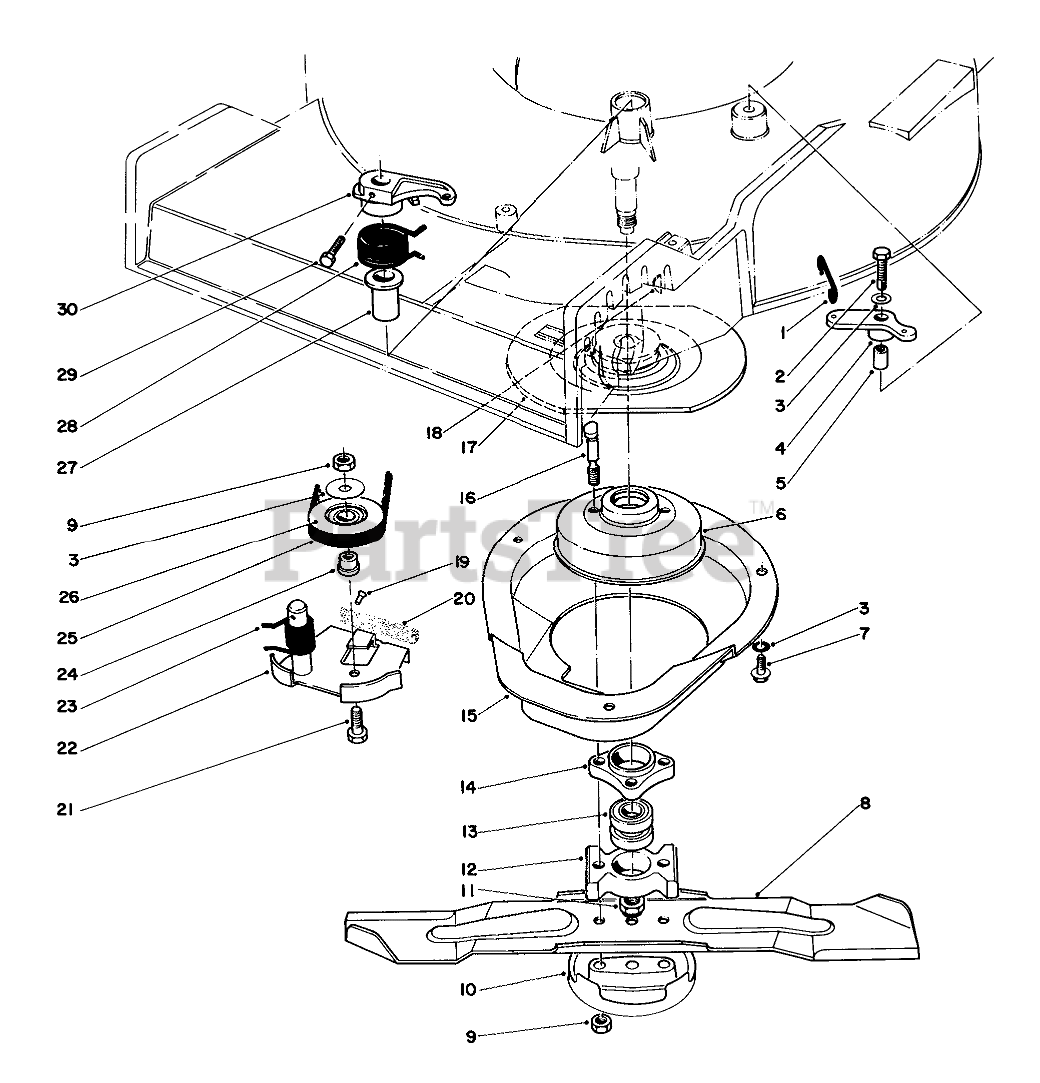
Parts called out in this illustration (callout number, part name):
1	Link Control
2	SCREW-HH
3	WASHER-FLAT
4	Bell Crank
5	Sleeve-Bell Crank
6	Brake Drum
7	SCREW-HWHTF
8	BLADE-21in
9	NUT-LOCK, NI
10	Anti Scalp Cup
11	NUT-LOCK, NI
12	Spacer Blade
13	BEARING-BALL
14	Hub Assembly (Incl. Ref. #13)
15	Shield
16	BOLT-BLADE
17	Flywheel
18	KEY-WOODRUFF
19	.185 DIA X .375 RT +
20	Paid
21	SCREW-HH
22	Brake Plate
23	SPRING-TORSION
24	HUB-PULLEY, IDLER
25	V-Belt
26	PULLEY-IDLER
27	BUSHING PM
28	TORSION SPRING
29	SCREW-HH
30	Lever
